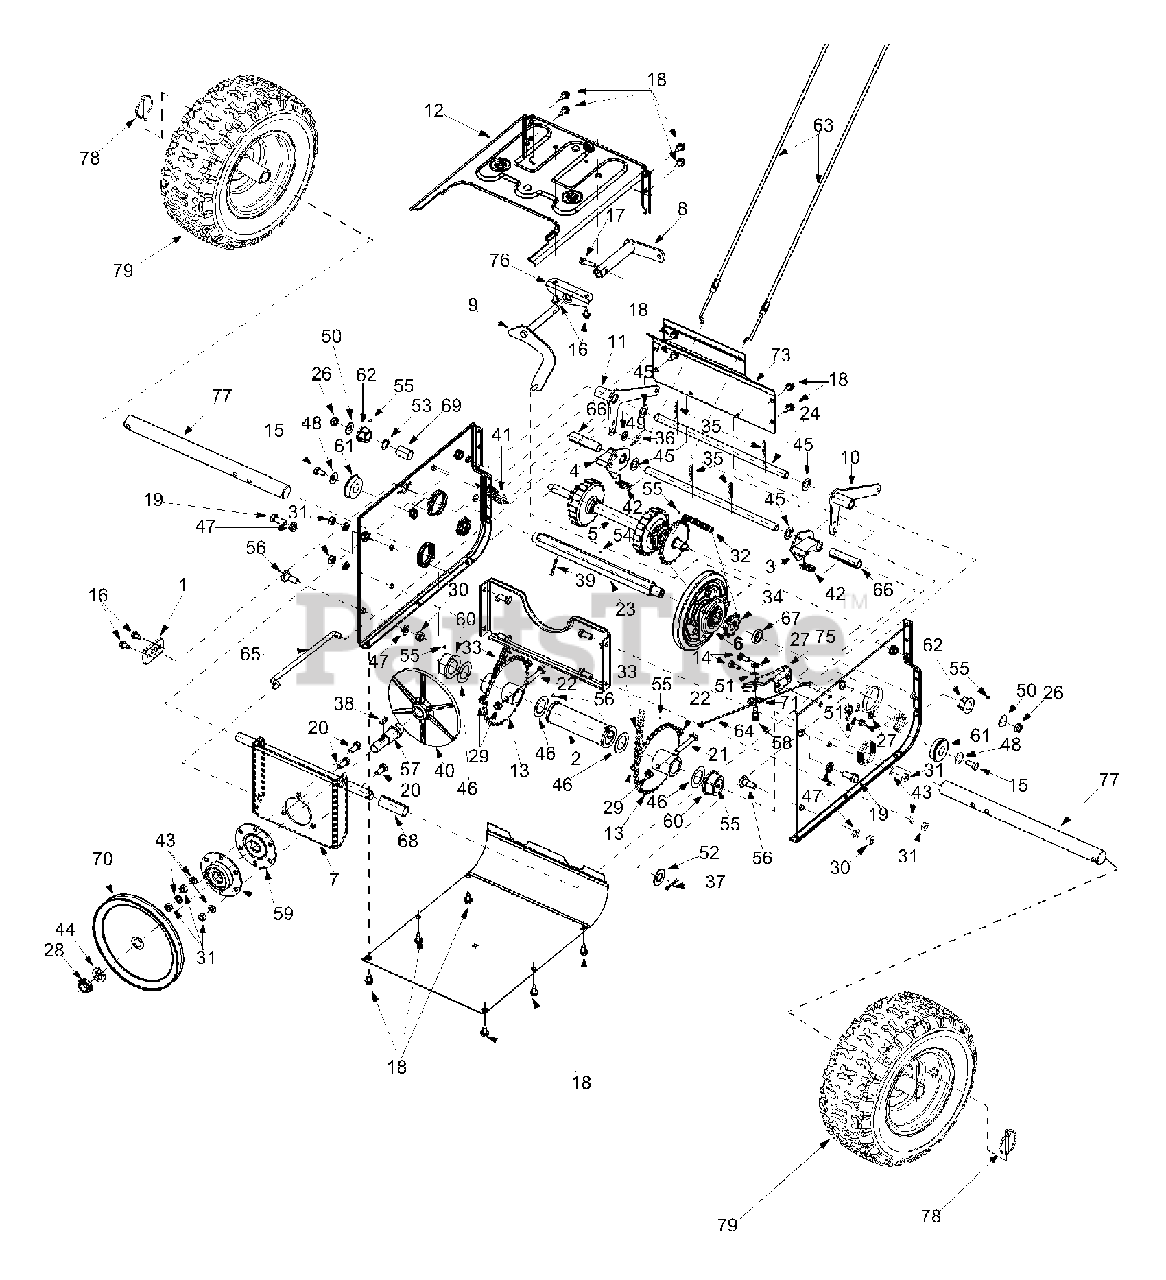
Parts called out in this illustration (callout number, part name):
1	Support Bracket: Pivot
2	Bush Assembly
3	Dogg Assembly LH
4	Dogg Assembly RH
5	Shift Assembly
6	Wheel Bearing Assembly
10	Auger Actuator Bracket Assy.
14	Hex Screw1/4-28 x .625"
15	Hex Screw5/16-18 x .625"
16	TT Screw 1/4-20 x .5"
17	TT Screw 1/4-20 x 1"
18	TT Screw1/4-20 x .625"
19	Hex Screw 3/8-16 x .880"
20	Hex Screw 5/16-18 x .75"
21	Hex Screw 5/16-18 x 2"
22	Hex Screw 5/16-18 x 1.75"
23	Hex Shaft: Drive
24	Actuator Shaft
26	Lock Nut
27	Hex Nut 1/4-28
28	Jam Lock Nut
29	Hex Lock Nut
30	Hex Nut 3/8-16
31	Hex Nut 5/16-18
32	Chain
33	Chain
34	Sprocket
35	Hairpin Clip
36	Hairpin Clip
37	Cotter Pin
38	Key
39	Roll Pin
40	Drive Plate
41	Extension Spring
42	Extension Spring
43	Lock Washer 5/16
44	Lock Washer 5/8
45	Flat Washer
46	Flat Washer
47	Lock Washer
48	Beleville Washer
49	Flat Washer
50	Flat Washer
51	Lock Washer
52	Flat Washer
53	Flat Washer
54	Lubricant
55	Grease
56	Shoulder Screw
57	Spindle: Drive Plate
58	Shoulder Screw 1/4-28 x .375"
59	Bearing Housing Assembly
60	Flange Bearing
61	Ball Bearing
62	Hex Flange Bearing
63	Steer Cable
64	Idler Cable: Auger
65	Clutch Rod: Drive
66	Split Spacer
67	Spacer
68	Split Spacer
69	Spacer
70	Drive Pulley
71	Roller Cable
77	Axle: Wheel
78	Klik Pin
